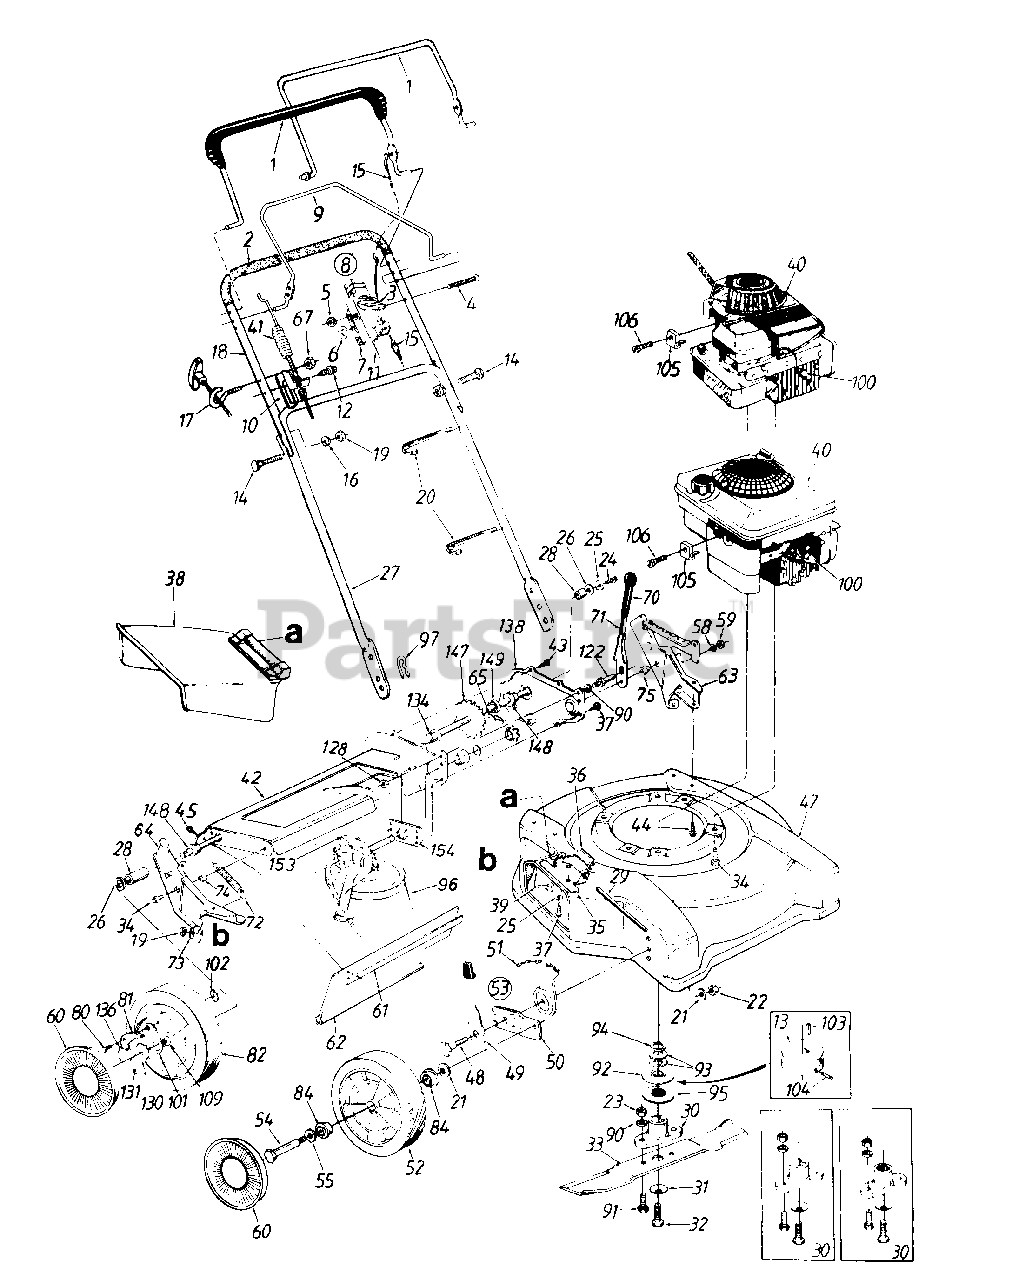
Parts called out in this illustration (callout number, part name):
2	Foam Grip
3	Throttle Lever
4	Oval C-Sunk Scr.
5	Hex L-Nut 1/4-20 Thd.
6	Spr. Wash..66" I.D.
7	Throttle Body
8	Throttle Box Comp.
9	S.P. Bail Ass'y.
10	Cable Bracket
11	Throttle Cable 55" Lg. (B&S)
12	Hex Wash. AB-Tap Scr. 5/16 x .75" Lg.
13	Keyed Pulley
14	Curved Carr. Bolt 5/16-18 x 1.38"
15	Control Cable 39" Lg. (B&S)
16	L-Wash. 5/16" I.D.
17	Rope Guide Bolt
20	Cable Tie
21	Bell-Wash..38" I.D. x .88"
22	Hex Nut 3/8-16 Thd.
23	Hex Nut 3/8-24 Thd.
24	Hex Bolt 1/4-20 x .62" Lg. (Grade 5)
25	Bell-Wash. 1/4" I.D.
26	Fl-Wash..531" I.D. x .93"
27	Lower Handle
28	Spacer.513" I.D. x .703"
29	Hinge Pin
30	Blade Adapter Kit
31	Bell-Wash..39" I.D.
32	Hex Bolt 3/8-24 x 1.5" Lg.
33	22" Blade
34	Hex L-Wash. Hd. Scr. 3/8-16 x 1.0" Lg.
35	Adapter Plate
36	Torsion Spring
37	Hex Self-Tap Scr. 1/4-20 x .5"
38	Chute Deflector Ass'y.
39	Carriage Bolt 5/16-18 x .62" Lg.
40	Engine
41	Drive Cable - 41.5" Lg.
44	Hex Wash. Hd. 8-Tap Scr. 5/16-18
45	Hex AB-Tap Scr. 1/4 x .62"
49	Spring Lever Ass'y. w/Knob
51	Height Adj. Plate
52	Wheel Ass'y. Comp.
53	Height Adj. Ass'y. Comp.- R.H.
54	Shld. Bolt .498" Dia. x 1.45"
55	Wave Wash..53" I.D. x .78"
58	Fl-Wash..385" I.D. x .87"
59	Hex Patch L-Nut 3/8-24 Thd.
60	Hub Cap
61	Retaining Strip
62	Rear Flap
63	L.H. Handle Wheel Brkt. Ass'y.
64	R.H. Handle Wheel Brkt. Ass'y.
65	#48 Chain .5" Pitch x 30 Links
67	Hex L-Nut 1/4-20 Thd.
71	Height Adj. Lever
72	Ext. Spring .5" O.D. x 3.8" Lg.
73	Bell-Wash. 5/16" I.D.
74	Spacer 383" I.D. x 503"
75	Shld. Spacer .5" Dia.
80	Shld. Scr..342" Dia. x .268"
81	Pawl
82	Wheel Ass'y. Comp.
84	Bearing
90	L-Wash. 3/8" I.D.
91	Hex Bolt 3/8-24 x 1.0" Lg.
92	Splined Pulley Half
93	Bell-Wash. 1.01" I.D.
94	Crankshaft Spacer
95	Lower Pulley Half
96	"V"-Belt
97	Hairpin Clip
100	Spark Plug Boot
101	Pawl Plate
102	Weld L-Nut 1/4-20 Thd.
103	Sq. Key 3/16" x 3/4" Lg.
104	Set Scr. 010-32 x .25" Lg.
105	Cable Clamp (B&S)
106	Hex Wash. Hd. Scr. #10-32 x .62" Lg. (B&S)
109	Sleeve Brg. 1/2" I.D.
122	Shld. Pin 3/8-24 x 1.43" Lg.
128	Hex Jam Nut 3/8-24 Thd.
130	Ratchet Wheel 1.62" O.D.
131	Cotter Pin 1/8" Dia.
134	Hex Flange Bearing
136	Spring - Nylon
148	Hex Flange Bearing
149	Fl-Wash..531" I.D. x .93"
153	Transmission Comp (See Breakdown)
